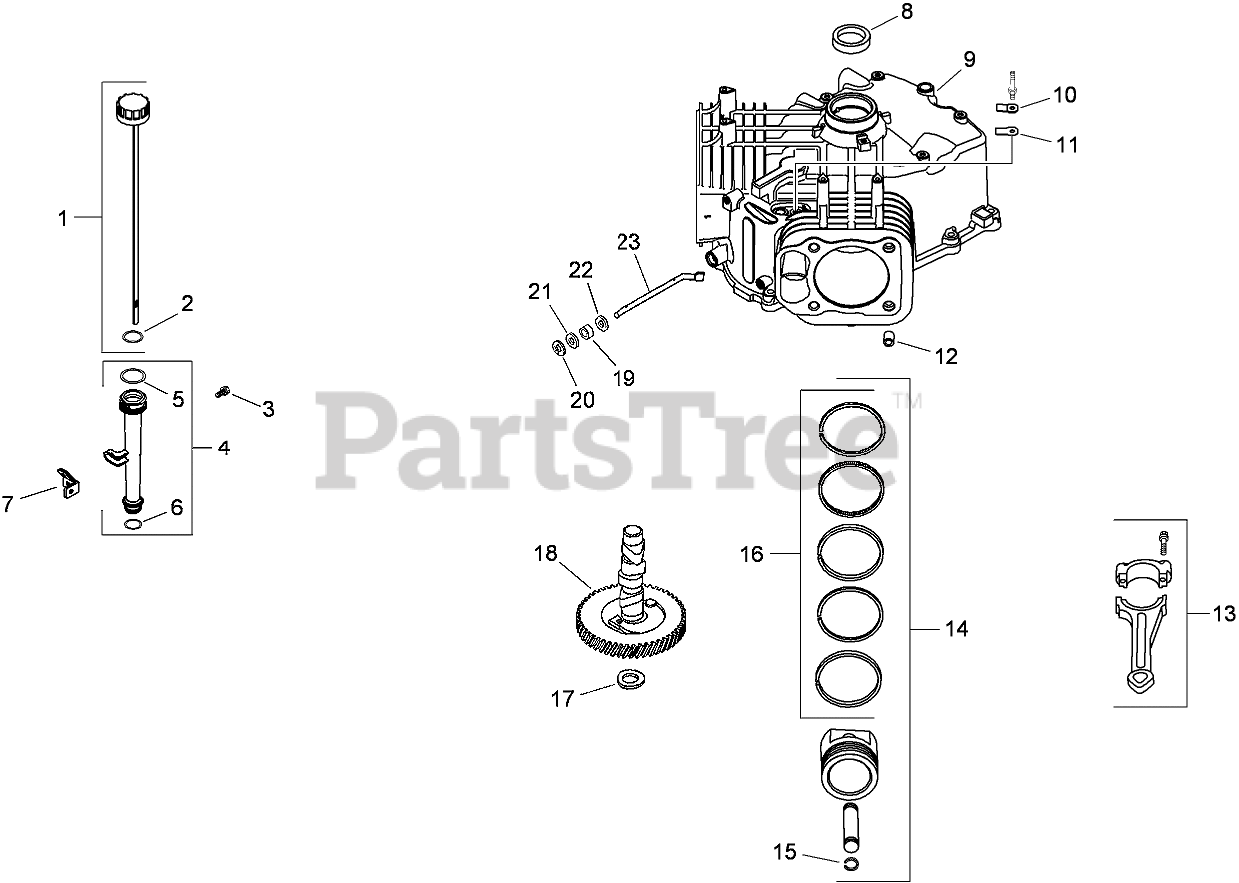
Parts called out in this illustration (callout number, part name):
1	DIPSTICK ASM
2	O-RING
3	SCREW-FLG, THD FRM (M5X0.8X13)
4	OIL FILL TUBE KIT (INCLUDES 5, 6)
5	O-RING (UPPER OIL FILL TUBE)
6	O-RING (LOWER OIL FILL TUBE)
7	BRACKET-TUBE, OIL FILL
8	SEAL-OIL
9	SHORTBLOCK (SV710-740)
10	RETAINER-REED, BREATHER
11	REED-BREATHER
12	PIN-LOCATING
13	ROD-CONNECTING (STD)
14	PISTON W/RING SET (STD)
14	PISTON W/RING SET (.25)
14	PISTON W/RING SET (.08)
15	RETAINER-PIN, PISTON
16	PISTON RING SET (STD)
16	PISTON RING SET (.25)
17	SHIM-CAMSHAFT (WHITE .028)
17	SHIM-CAMSHAFT (BLUE .03)
17	SHIM-CAMSHAFT (RED .032)
17	SHIM-CAMSHAFT (YELLOW .034)
17	SHIM-CAMSHAFT (GREEN .036)
17	SHIM-CAMSHAFT (GRAY .038)
17	SHIM-CAMSHAFT (BLACK .04)
18	CAMSHAFT KIT
19	SEAL-CROSS SHAFT, GOVERNOR
20	RETAINER-RING
21	WASHER-FLAT (9MM)
22	WASHER-FLAT (11/32)
23	SHAFT-CROSS, GOVERNOR
